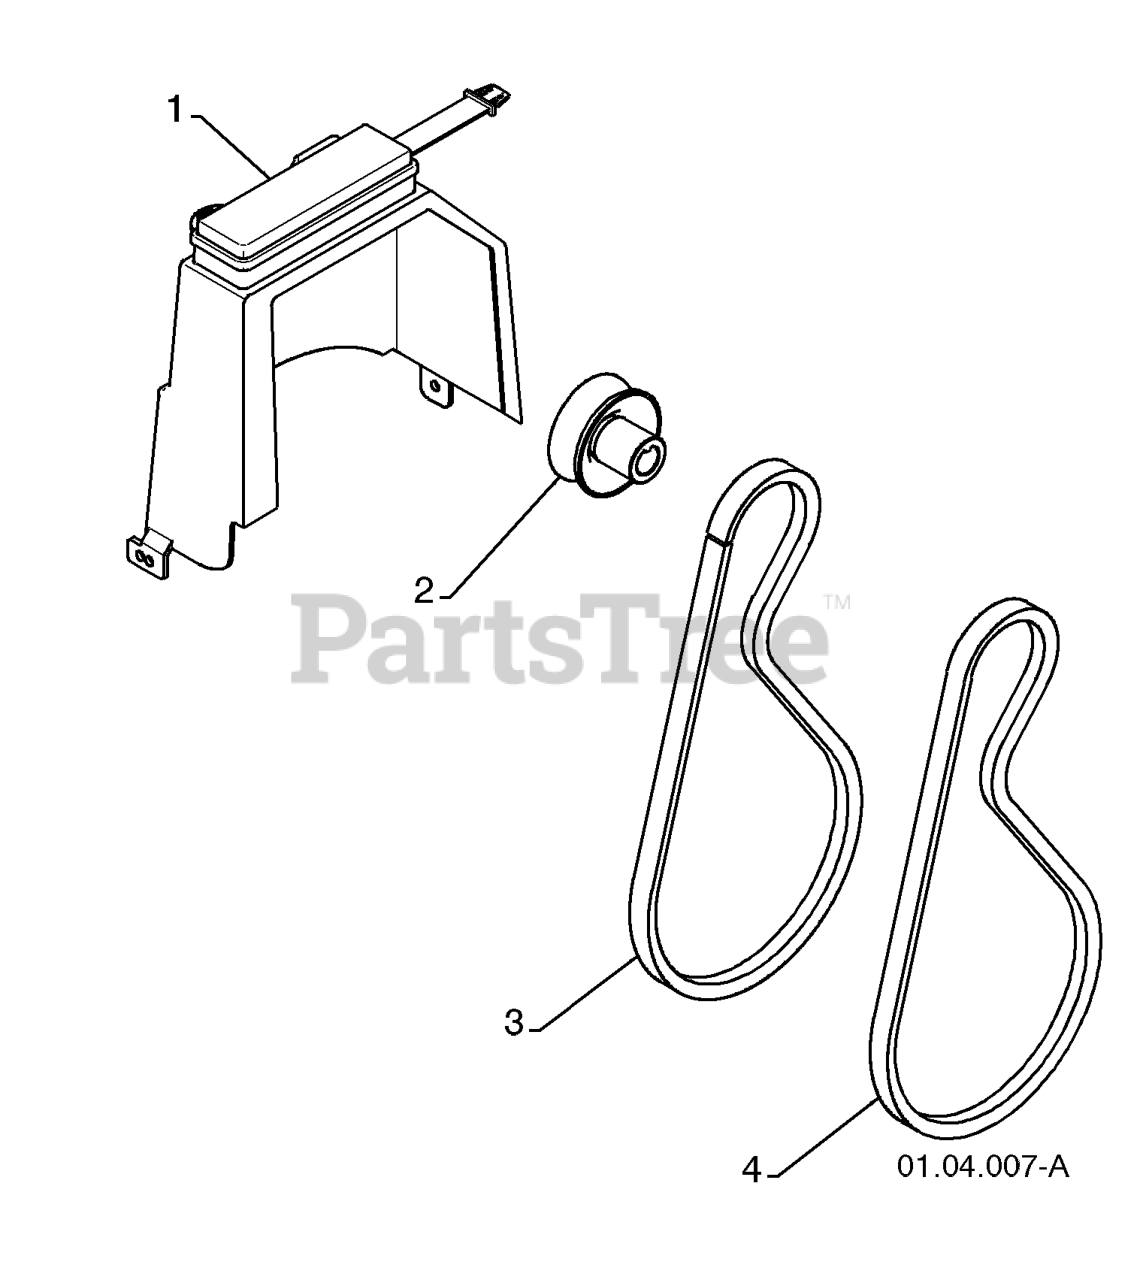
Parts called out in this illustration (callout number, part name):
1	COVER.ASM.BELT/STORAGE
2	PULLEY, ENGINE IMPELLER DRIVE
3	V-BELT TRACTION 34.25
4	BELT.V.IMPELLER.DRIVE
